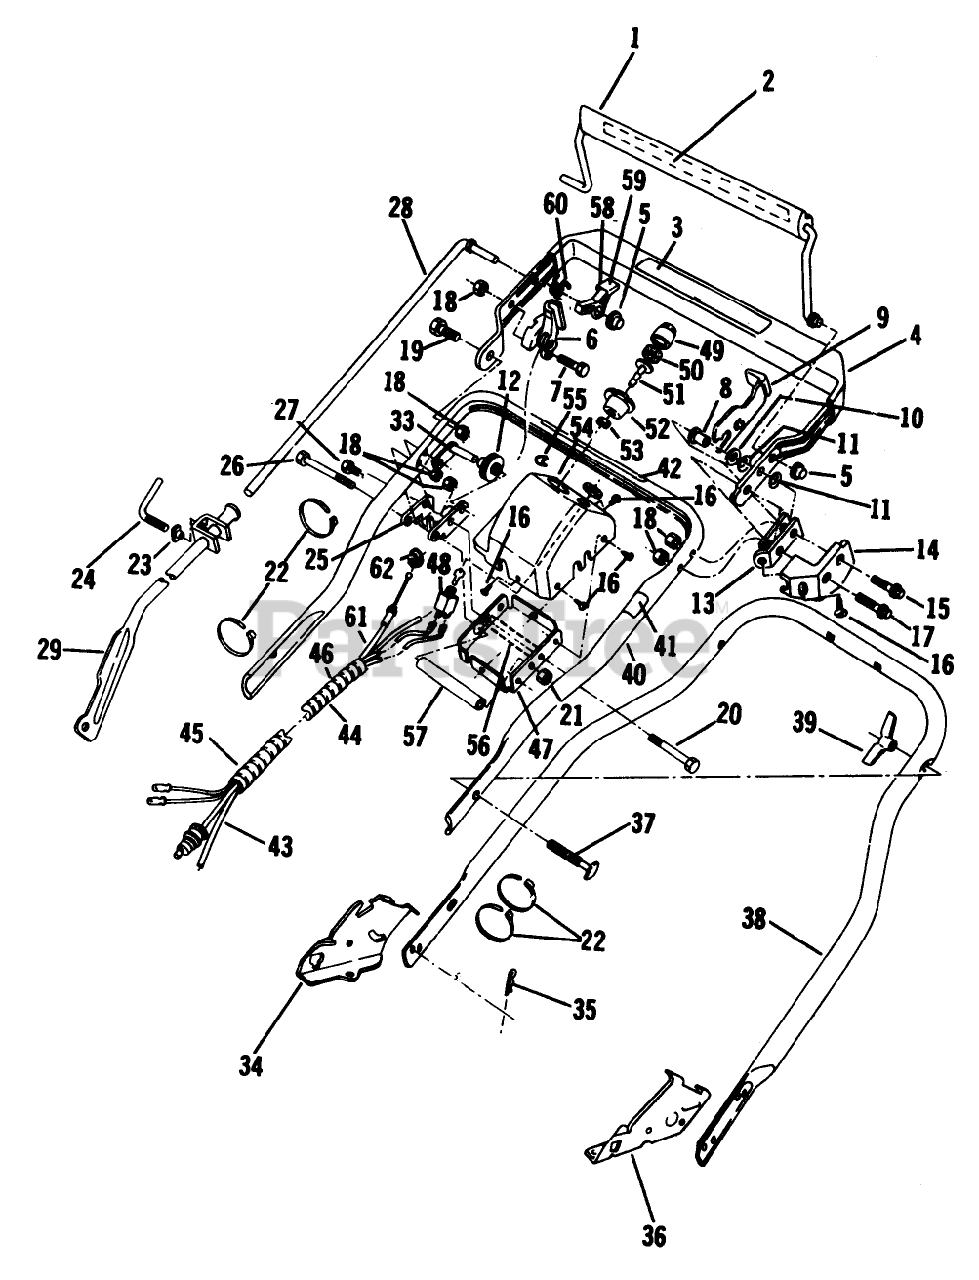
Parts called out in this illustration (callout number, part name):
8	SPACER
10	WASHER M
13	DOWN STOP
14	LOCKOUT GUARD
15	BOLT SHOU
16	SCREW F
17	SCREW
18	LOCKNUT E
19	BOLT
26	BOLT-CONSOLE
29	Control Lever Assembly
34	BRACKET ASM - HANDLE, SP, RH
35	HAIR PIN
36	BRACKET ASM - HANDLE, SP, LH
37	BOLT QUALITY
39	NUT-WING
48	SWITCH AY
50	FILTER S
53	LOCKNUT S
56	SPACER
61	CONTROL CABLE
62	RET. RING
